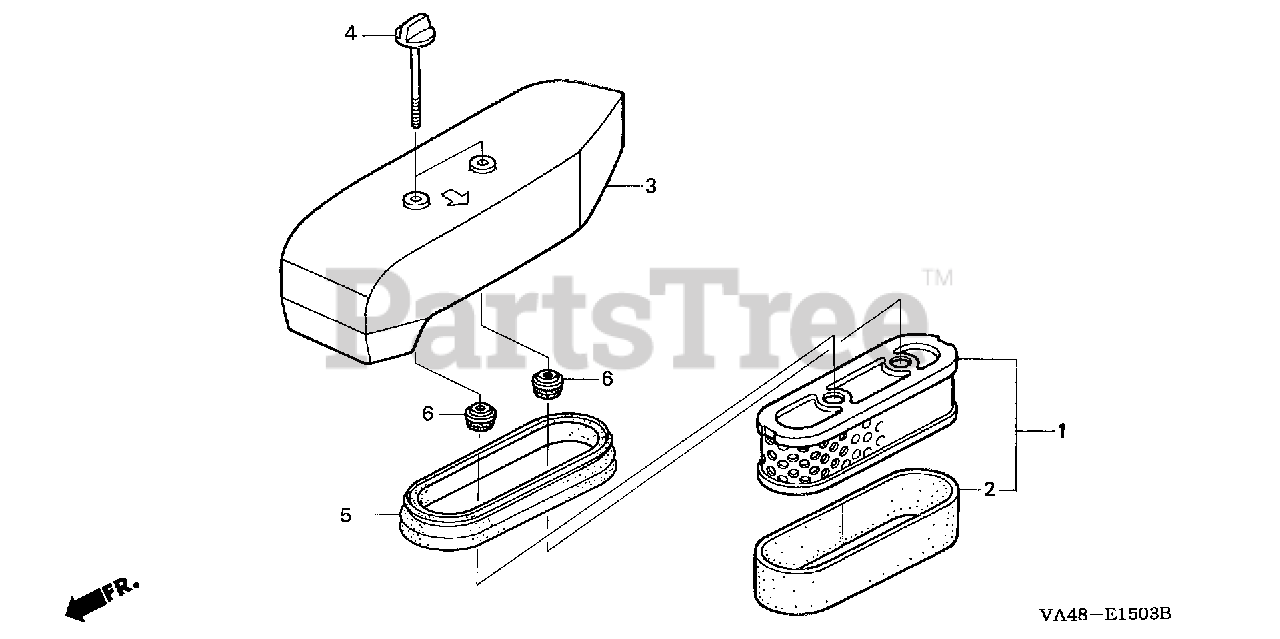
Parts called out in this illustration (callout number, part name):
1	ELEMENT, AIR CLEANER (TOYO)
2	FILTER (OUTER)
3	COVER, AIR CLEANER *NH1* (BLACK)
4	BOLT, AIR CLEANER (6X73)
5	GASKET, ELEMENT
6	GROMMET, AIR CLEANER
